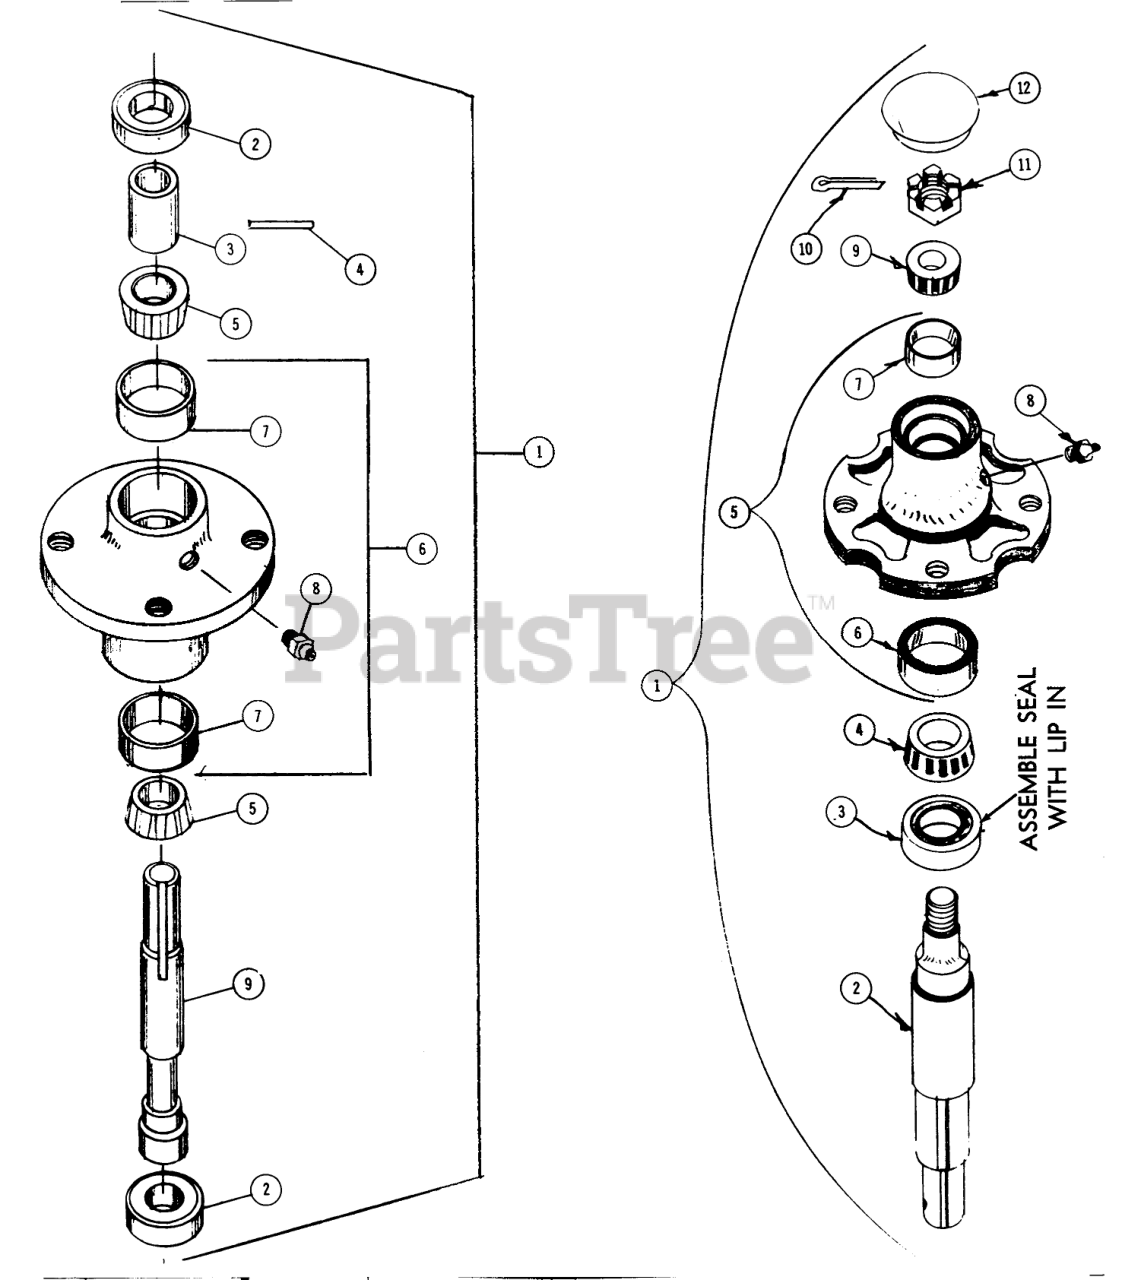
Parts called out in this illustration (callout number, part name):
1	Spindle Assembly (For Left Hand Rotation)
1	Drive Spindle Assembly Complete
2	Drive Spindle Shaft
3	Sleeve
4	Self-lock Pin
5	Hub With Cups
6	Housing With Cups
8	Grease Fining
8	Sweep Shovel
9	Clamp Plate
9	Cone
10	Cotter Pin
11	3/4 NF Castle Nut
12	Hub Cap
